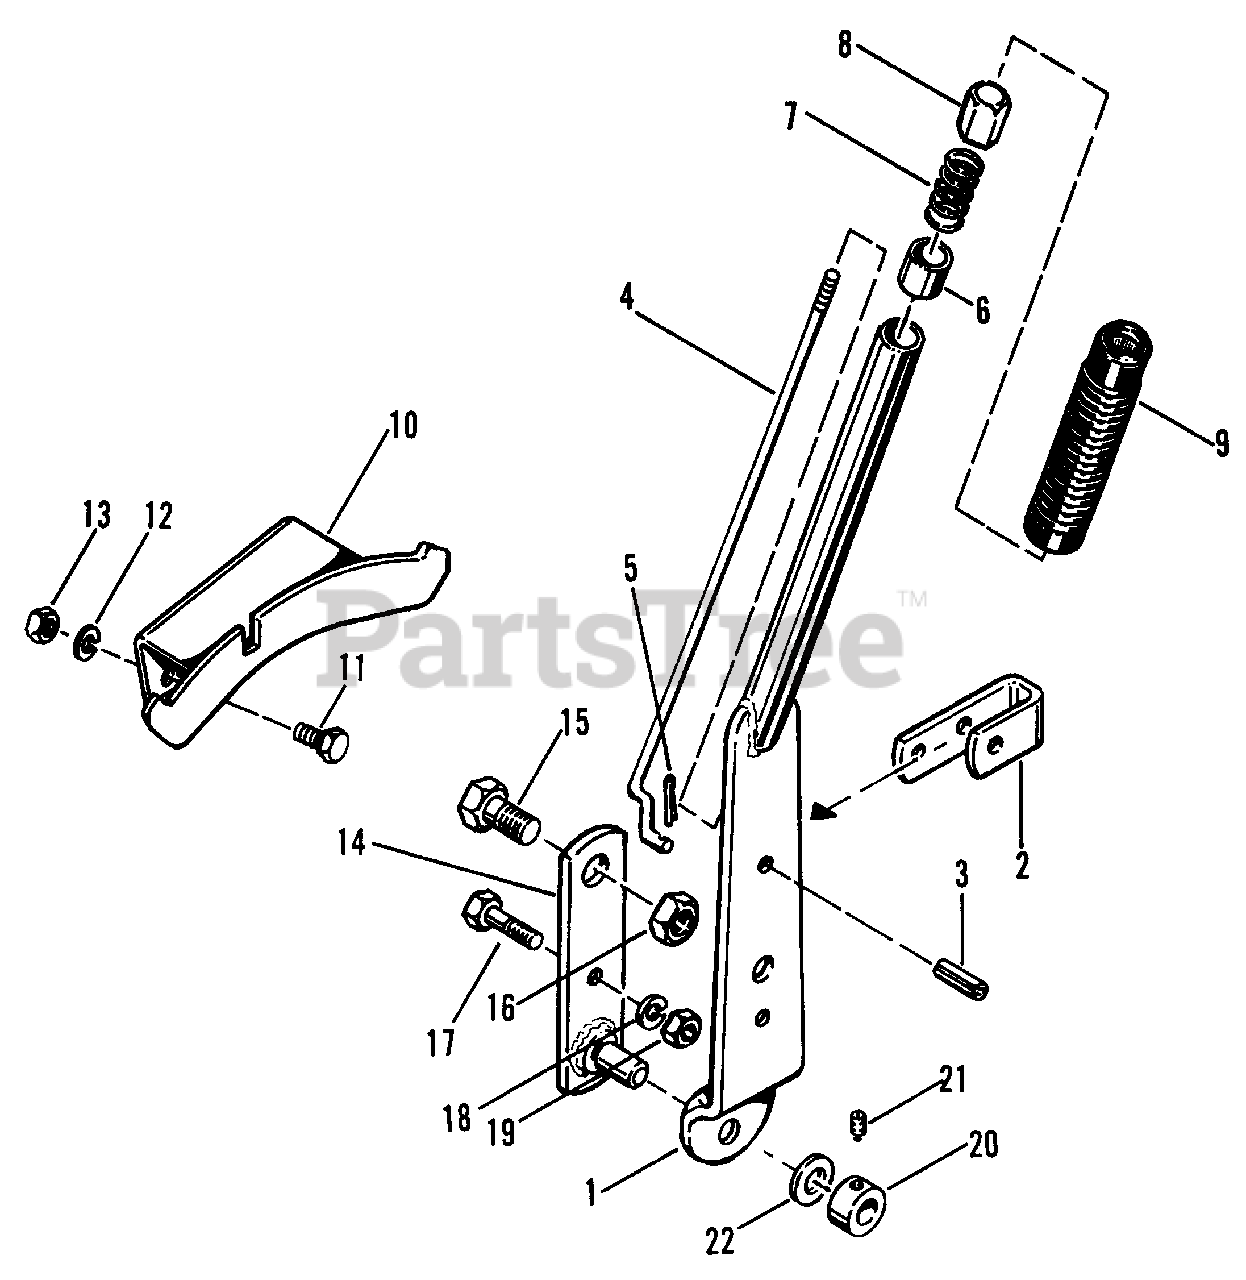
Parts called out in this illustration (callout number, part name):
1	Lift Lever Assembly
2	Lift Lever Latch
3	Roll Pin, 3/8"-1"
4	Latch Rod
5	Cotter Pin
8	Thumb Button
9	Handle Grip
10	Quadrant Assembly
11	Hex Capscrews, 3/8"-16 x 3/4" lg.
12	Lock Washer, 3/8"
13	Hex Nut, Full, 3/8"-16
14	Front Lift Lever Assy.
15	Hex Capscrew, 1/2"-13 x 1"
16	Center Lock Jam Nut, 1/2" 13
17	Hex Capscrew, 3/8"-16 x 1-1/4" lg.
18	Lock Washer, 3/8"
19	Hex Nut, 3/8"-16
20	Set Collar
21	Set Screw, 5/16"-18 x 1/4" lg.
22	Plain Washer, 1/2"
